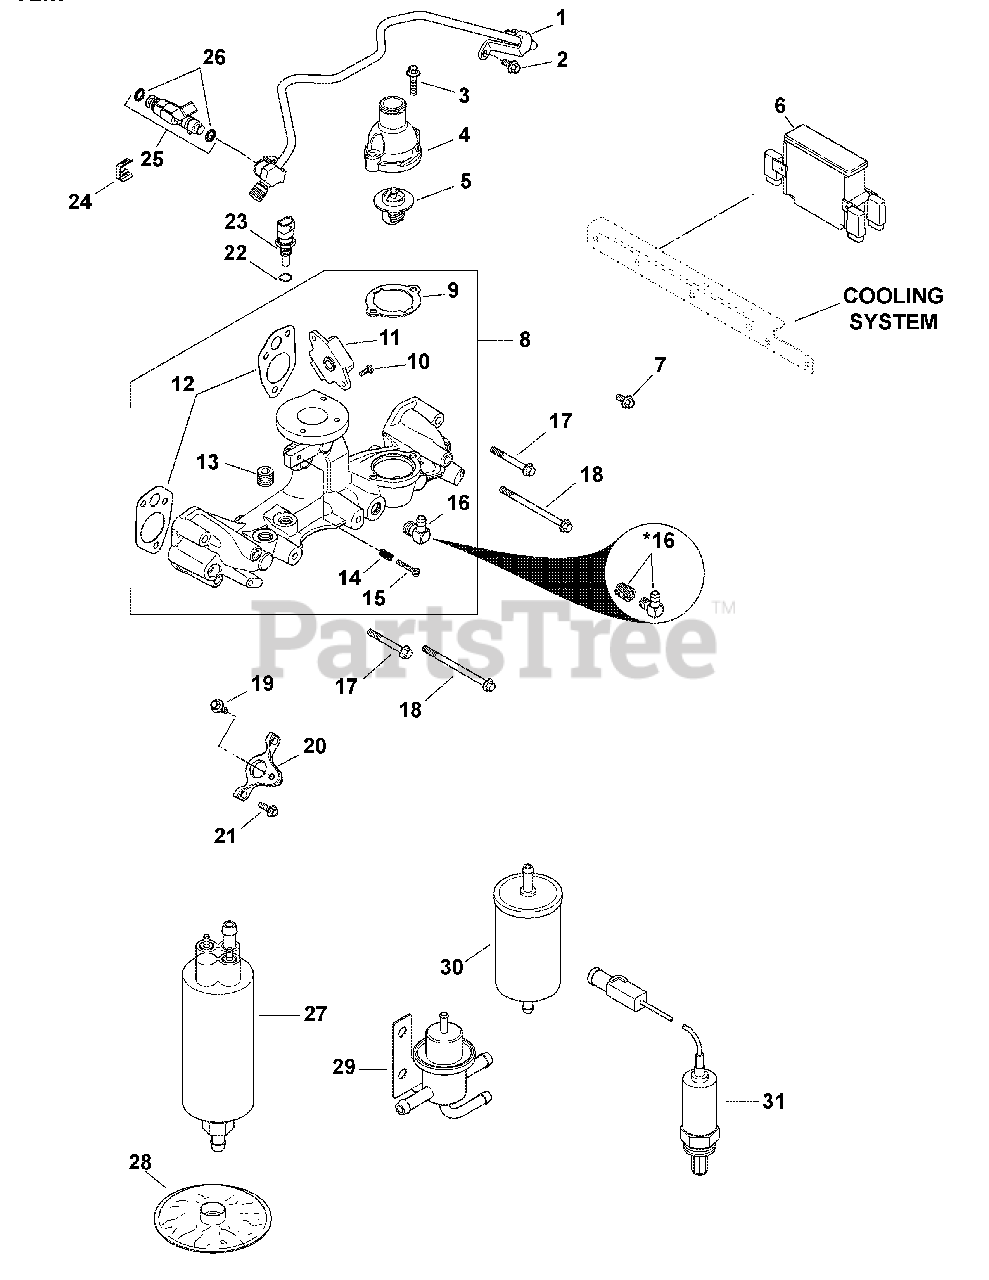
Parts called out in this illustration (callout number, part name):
2	Screw, Flg, M6 x 1.0 x 12
3	Screw, Flg, M6 x 1.0 x 25
4	Housing, Thermostat
5	Kit, Thermostat
6	Module, Engine Mngmnt. (ECU)
7	Screw, Flg, M6 x 1.0 x 12
8	Kit, EFI Intake Manifold
9	Gasket, Thermostat
10	Screw, Phl Pan, M4x0.7x12
11	Kit, Throttle Position Sensor
12	Gasket, Intake Manifold
13	Plug, Pipe Ctsk, 3/8"
14	Spring, Speed Control (Short)
15	Screw, Phl Pan M4 x 0.7 x 25
16	Connector, Hose
17	Screw, Flg M6 x 1.0 x 50
18	Screw, Flg M6 x 1.0 x 90
19	Screw, Flg Thd Frm M6x1.0x16
20	Bracket, Speed Sensor
21	Screw, Flg Thd Frm M5x0.8x16
23	Sensor, Temperature
24	Clip, Fuel Injector
25	Injector, Fuel
27	Pump Ass’y, Fuel
28	Filter, Fuel Strainer
29	Regulator Ass’y, Fuel Pressure
30	Fuel Filter, High Pressure
31	Sensor, Oxygen
